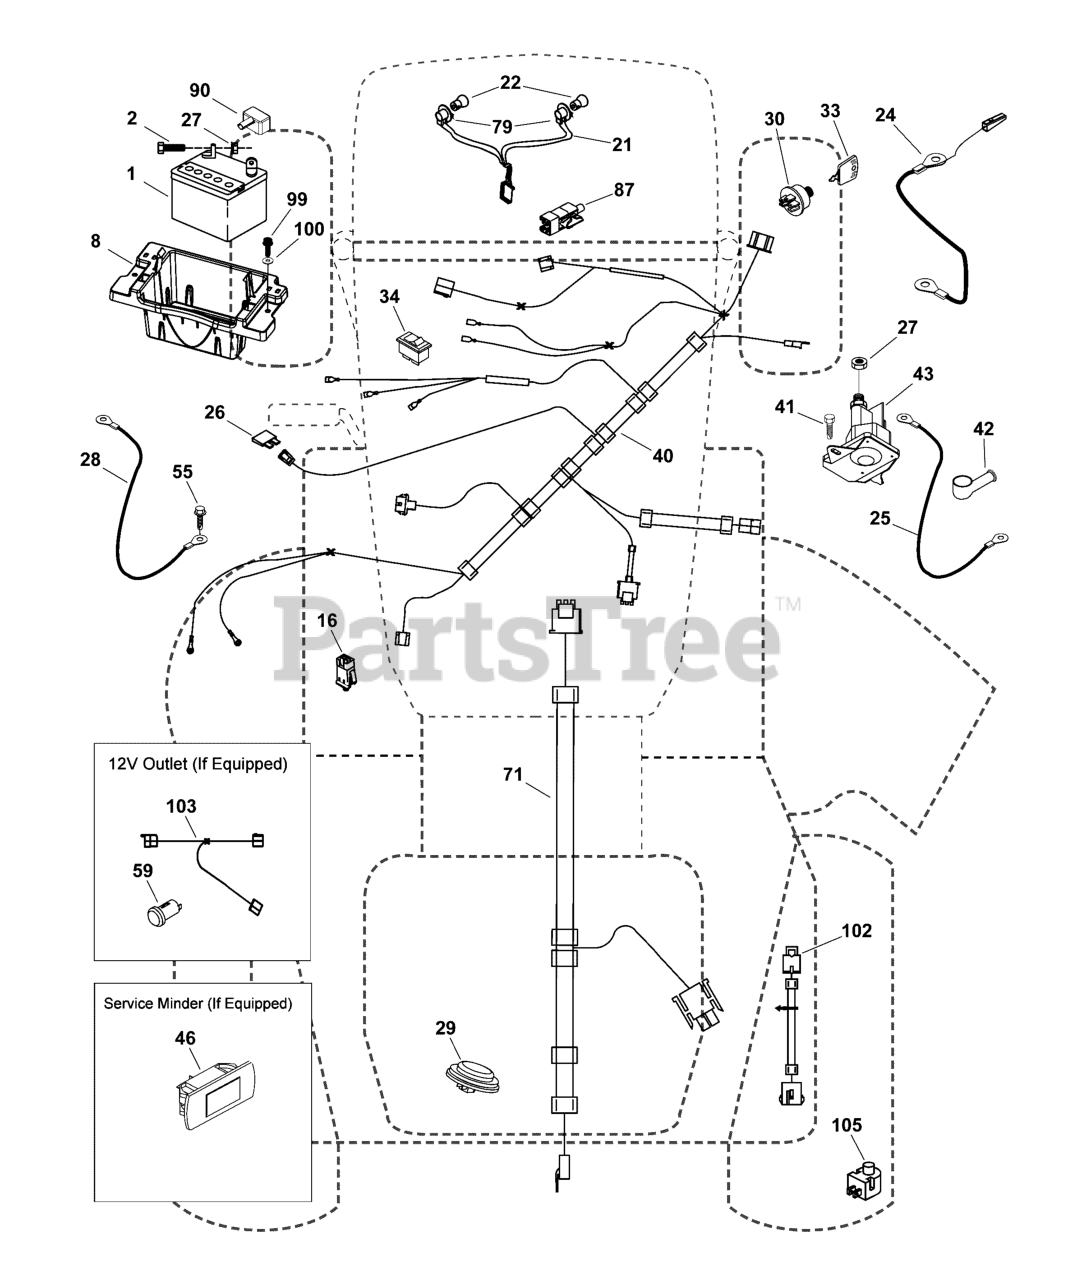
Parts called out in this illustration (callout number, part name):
1	Battery
2	Bolt Hex Head 1/4-20 x 3/4
8	BOX, Battery
16	Switch Interlock Push-In
21	Harness Socket Light w/4152J
22	Bulb Light
24	Cable Battery
25	Cable Starter
27	Nut Keps Hex 1/4-20 unc
28	Cable, Ground
29	Switch, Seat
30	SWITCH, IGNITION
33	Key/Chain
34	Switch Light/Reset
40	HARNESS, Ignition Dash
41	Screw Thd Cut 1/4-20 x 1/2
42	Cover, Terminal
43	SOLENOID
46	GAUGE, Service Minder Hour Meter
55	Screw 5/16-18 X 3/4 Smgml Tap/R
71	HARNESS, Ignition Chassis
79	Socket Asm Bulb Twistlock
87	Switch Interlock Clutch Cable
90	Cover Terminal Battery
99	Screw Hexwsh Thdrol 1/4-20 x 3/4
100	Washer 9/32 x 7/8 x 16 Ga.
102	Harness Pigtail
105	Switch Reverse
